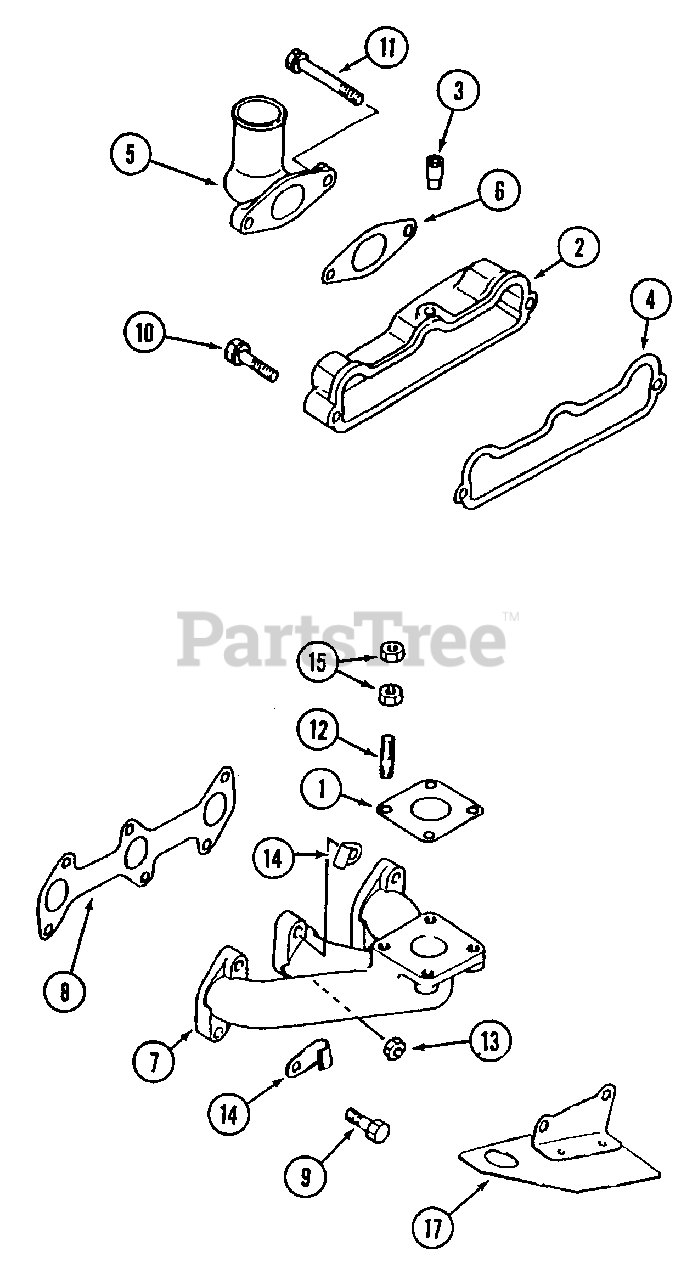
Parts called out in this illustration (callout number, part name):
2	Intake Cover Ass'y.
3	Pipe
4	Gasket, Intake Manifold
5	Pipe, Inlet
6	Gasket, Inlet Pipe
7	Manifold, Exhaust
8	Gasket, Exhaust Manifold
10	Bolt, w/Washer
11	Bolt, w/Washer
12	Stud
14	Clamp, Tachometer Cable
17	Cover, Starter
